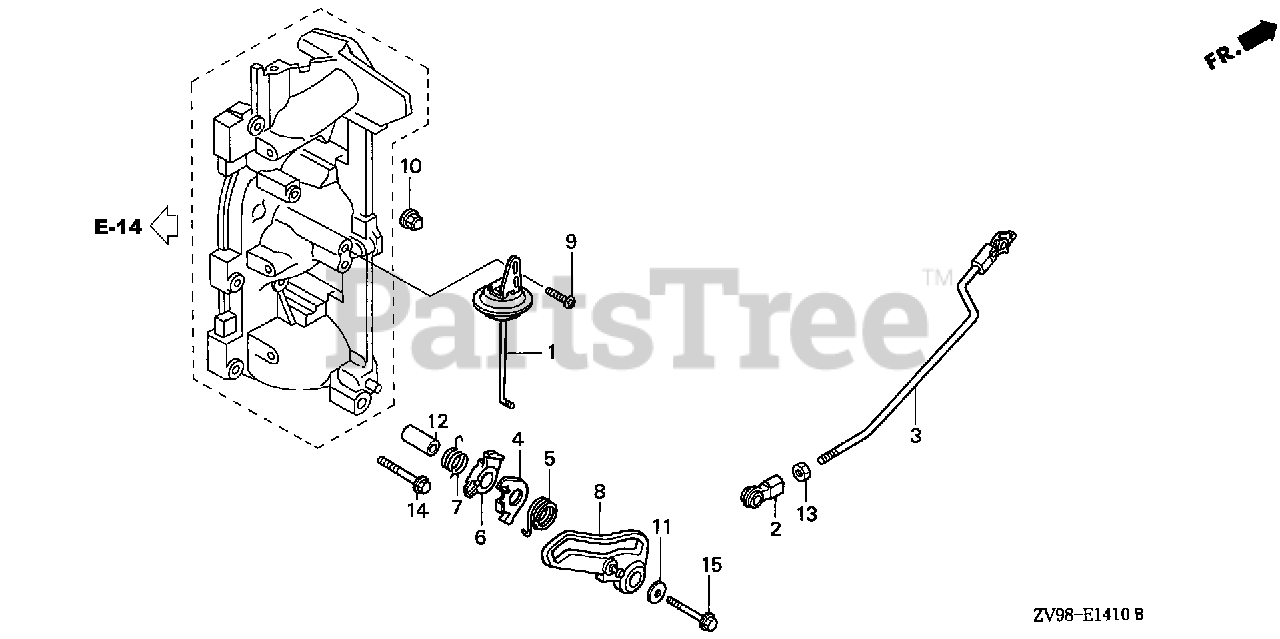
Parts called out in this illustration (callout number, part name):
1	DIAPHRAGM ASSY.
2	LINKAGE, PIVOT
3	ROD, THROTTLE
4	PLATE, ASSIST
5	SPRING, ASSIST
6	CAM, THROTTLE OPENER
7	SPRING, OPENER CAM RETURN
8	CAM, THROTTLE
9	BOLT, TORX (6X14)
10	NUT, CAP (6MM)
11	WASHER, PLAIN (6MM)
12	COLLAR (6.7X12.5X24)
13	NUT, HEX. (5MM)
14	BOLT, FLANGE (6X32)
15	BOLT, FLANGE (6X40)
